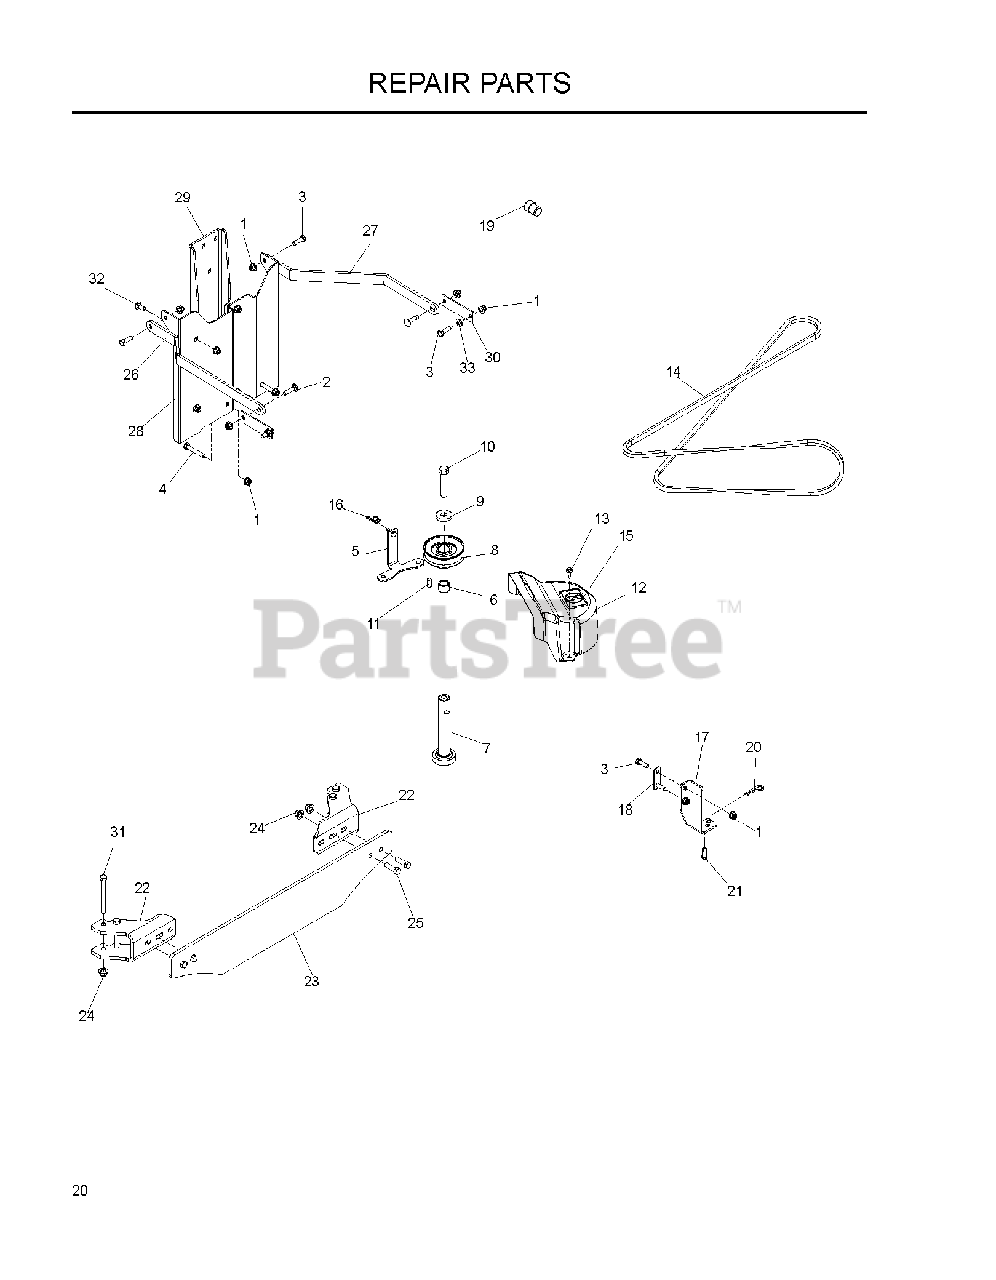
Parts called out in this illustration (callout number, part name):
1	5/16-18 NYLOC FLANGE NUT
2	BOLT, CARRIAGE 5/16X1-1/4
3	HCS 5/16C X 1
4	HCS 5/16-18X2
5	BELT SHIELD STANDOFF - 44
6	SPACER, DRIVE PULLEY - .680"
8	PULLEY, SPDZTR 44
9	WASHER .525 X 1.375 X .25
10	BOLT, 1/2-20 X 2-1/2
11	OUTER SHAFT KEY
12	SHIELD, BELT - 44 SPDZTR
13	SCREW, TAP & DR #12-14 X 3/4
14	BELT A-83 KEVLAR
15	DECAL, NO STEP
16	WING NUT 1/4
17	BRACKET, HOLD DOWN
18	PLATE, BACK UP
19	SPACER PLUG, BAGGER
20	RETAINER SPRING
21	CLEVIS PIN
22	BRACKET WEIGHT BLK
24	NUT 3/8-16 HEX FLG NYLOC ZD
25	HCS 3/8C X 1 1/4
26	STRAP, SUPPORT, RT BLK
27	STRAP, SUPPORT, LT BLK
28	MOUNT, 2 BIN COLLECT, BLK
29	BRACKET, COLLECTION BLK
30	REINFORCEMENT PLATE BLK
32	BOLT 5/16C X 3/4" CARRIAGE
33	FLAT WASHER 5/16 SAE
